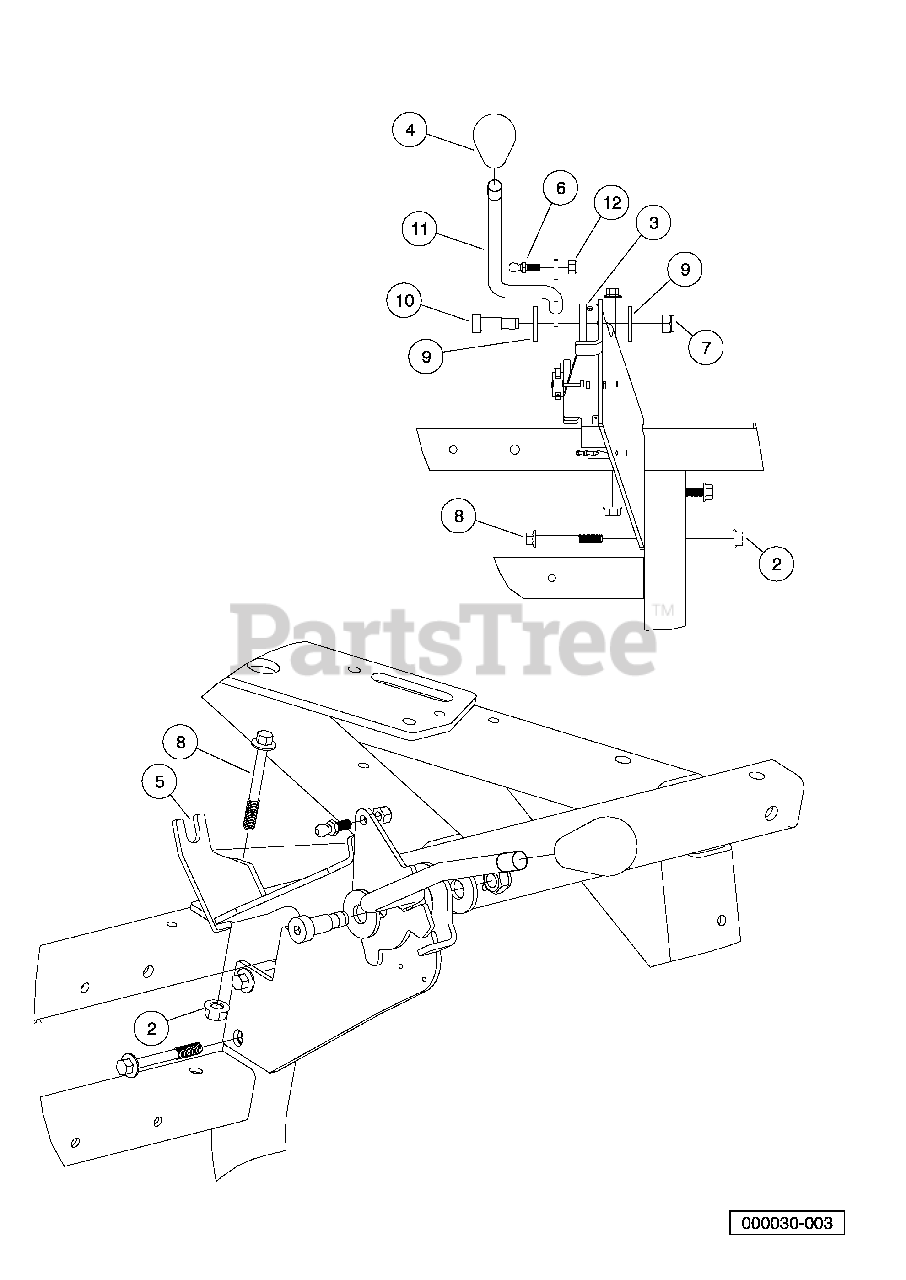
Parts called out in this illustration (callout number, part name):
1	Instl, Fnr, Shifter, Dom
2	Nut,m8,all Metal Lock
3	Bushing, Fnr
4	Knob, Fnr.
5	Weldment, FNR Shifter Bracket
6	Stud, Ball, .346 Dia
7	Locknut, M10x1.5 Nylon Insert
8	Bolt Flanged Head, M8 X 1.25 X 65
9	Washer, M12 Hard Regular
10	Shoulder Bolt,m12 X 20 M10 Thd
11	Weldment, FNR Shifter
12	Locknut, 1/4-28 Nylon Insert
13	Tie Wrap, 8" Nylon
